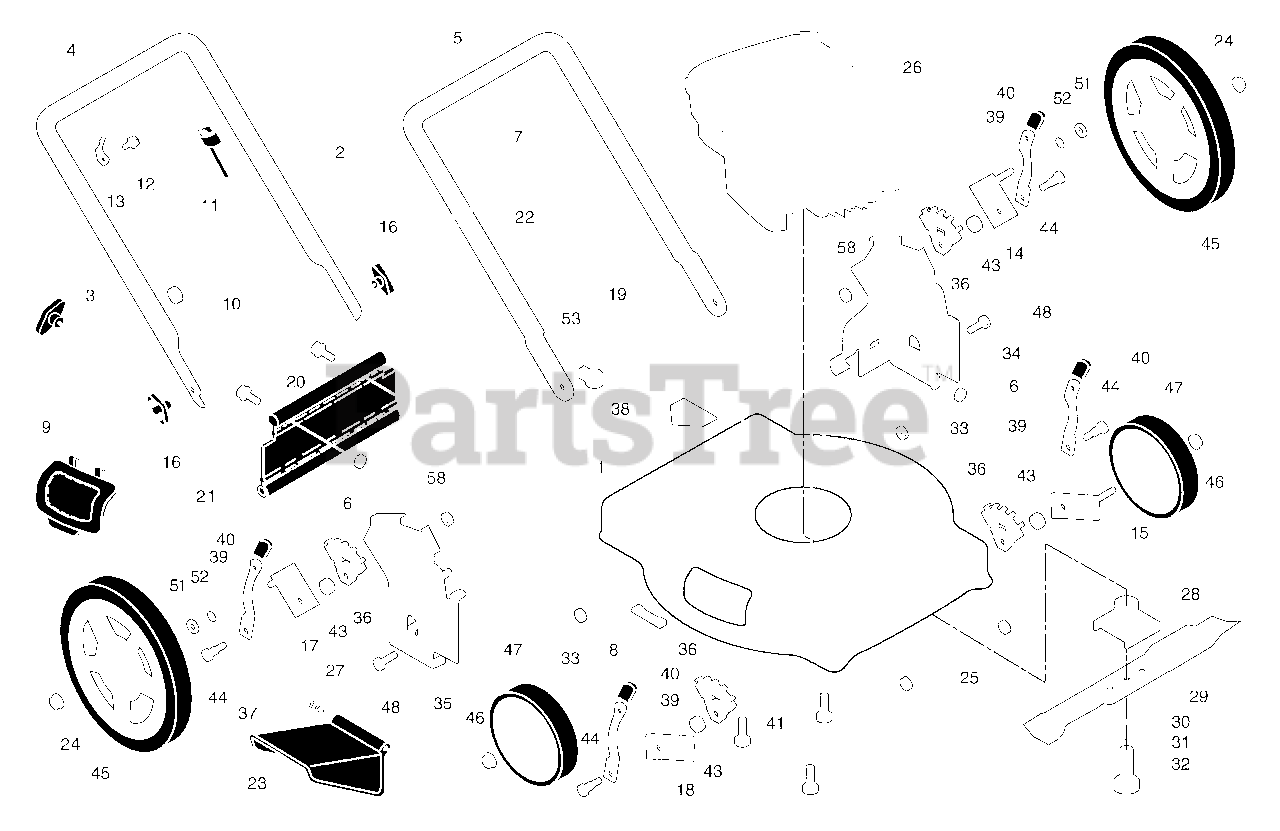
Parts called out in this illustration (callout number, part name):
1	Lawn Mower Housing
2	Control Bar
3	Rope Guide
4	Upper Handle
5	Lower Handle
6	Locknut, Hex 1/4-20
7	Handle Bolt 5/16-18
8	Clip, Closeout
9	Plate, Mulcher
10	Locknut, Hex 1/4-20
11	Engine Zone Control Cable
12	Hex Washer Head Screw #10-24 x 1/2
13	Up-Stop Bracket
14	Axle Arm Assembly, Rear, LH
15	Axle Arm Assembly, Front, LH
16	Handle Knob
17	Axle Arm Assembly, Rear, RH
18	Axle Arm Assembly, Front, RH
19	Hairpin Cotter
20	Screw, Hex Cap Head 1/4-20
21	Rear Deflector
22	Wire Tie
23	Discharge Guard
24	Nut, Hex, Flangelock 3/8-16
25	Nut, Hex, Flangelock 5/16-18
27	Torsion Spring
28	Blade Adapter
29	22" Blade
30	Hardened Washer
31	Helical Lockwasher 3/8
32	Screw, Hex Head 3/8-24 x 1-3/8(Grade 8)
33	Nut, Hex, Nylock 5/16-18
34	Handle Bracket, LH
35	Handle Bracket, RH
36	Wheel Bracket Adjuster
37	Hinge Rod
38	Danger Decal
39	Selector Spring
40	Selector Knob
41	Hex Head Thread Rolling Screw 3/8-16 x 1
43	Spacer
44	Shoulder Bolt 5/16-18
45	Wheel & Tire Assembly, Rear, 12"
46	Nut, Hex, Flangelock 3/8-16
47	Wheel & Tire Assembly, Front, 8"
48	Hex Head Bolt 5/16-18
51	Washer, Flat
52	O-Ring
53	Clip, Cable
58	Nut, Hex, Nylock 5/16-18
